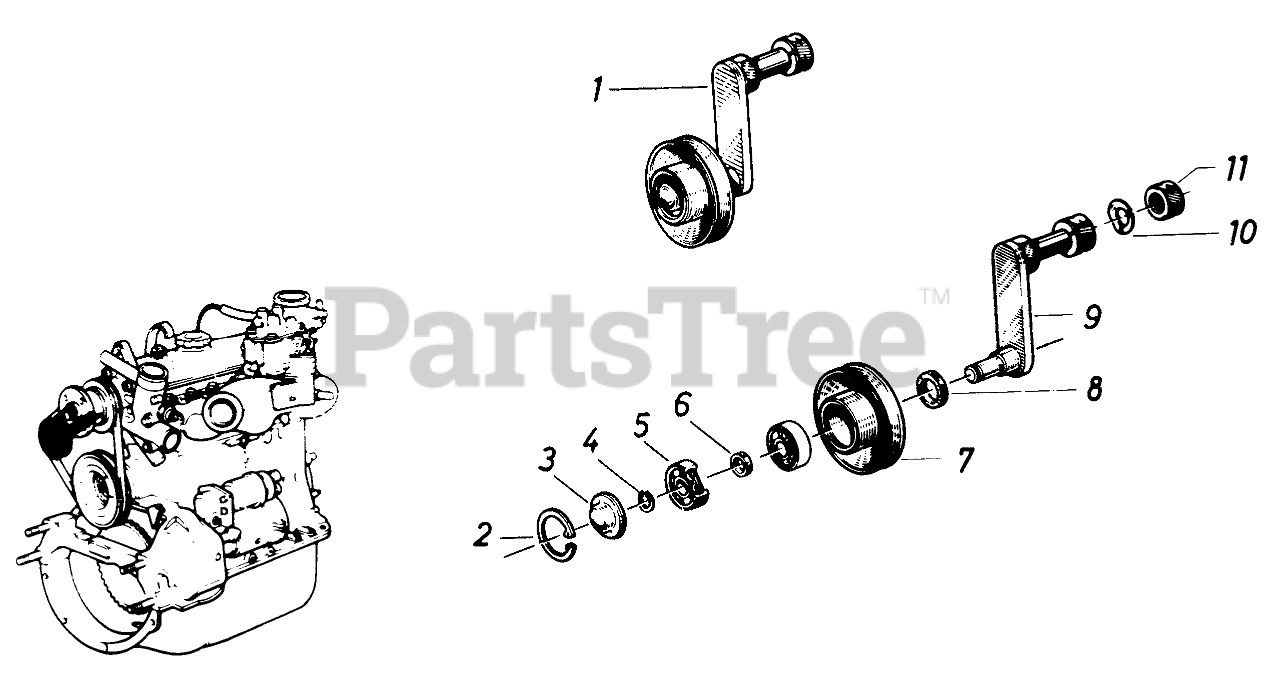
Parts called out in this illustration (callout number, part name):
1	Idler Pulley Cpl.
2	Snap Ring
3	Cover
4	Lock Washer
5	Ball Bearing
6	Spacer
7	Idler Pulley
8	Felt Ring
9	Idler Arm
10	Washer
